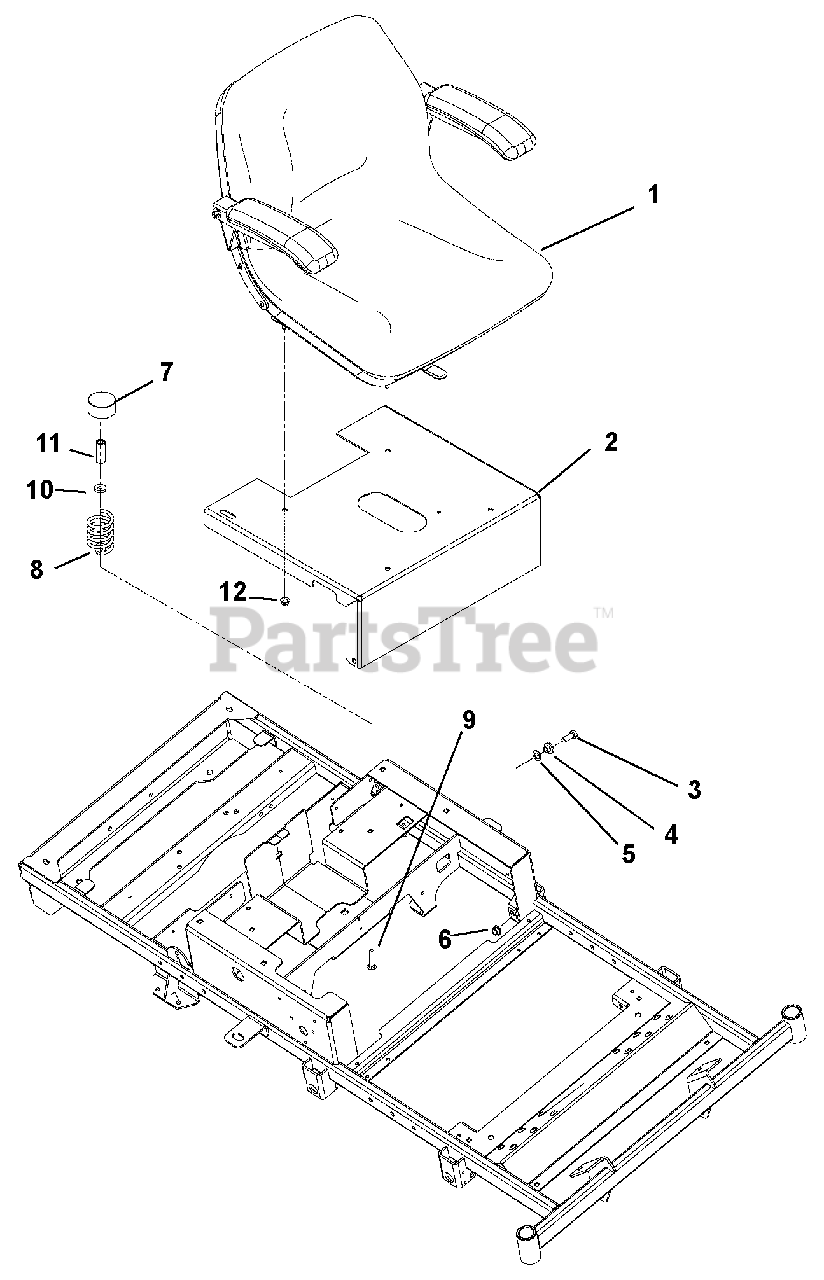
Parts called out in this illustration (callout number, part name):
1	SEAT, MILSCO XB-180
1	SWITCH- SNAP MTG N.O.
2	SEAT PLATE
3	@BLT-HEX .38-16X1.00 GR5 YWZC
4	BSHG-FLG .385X.500X.875X.406
5	WSHR-FL-STL .52X.827X.062 YWZC
6	@NUT-LK-NYL-FLG .38-16 YWZC
7	HUB CAP
8	SPRING, SEAT
9	@BLT-RDHDSQNK .31-18X1.50 G5YZ
10	WSHR-FL-STL .328X.87X.179 YWZC
11	NUT, COUPLING 5/16-18 X 1 3/4
12	@NUT-LK-NYL-FLG .31-18 YWZC
